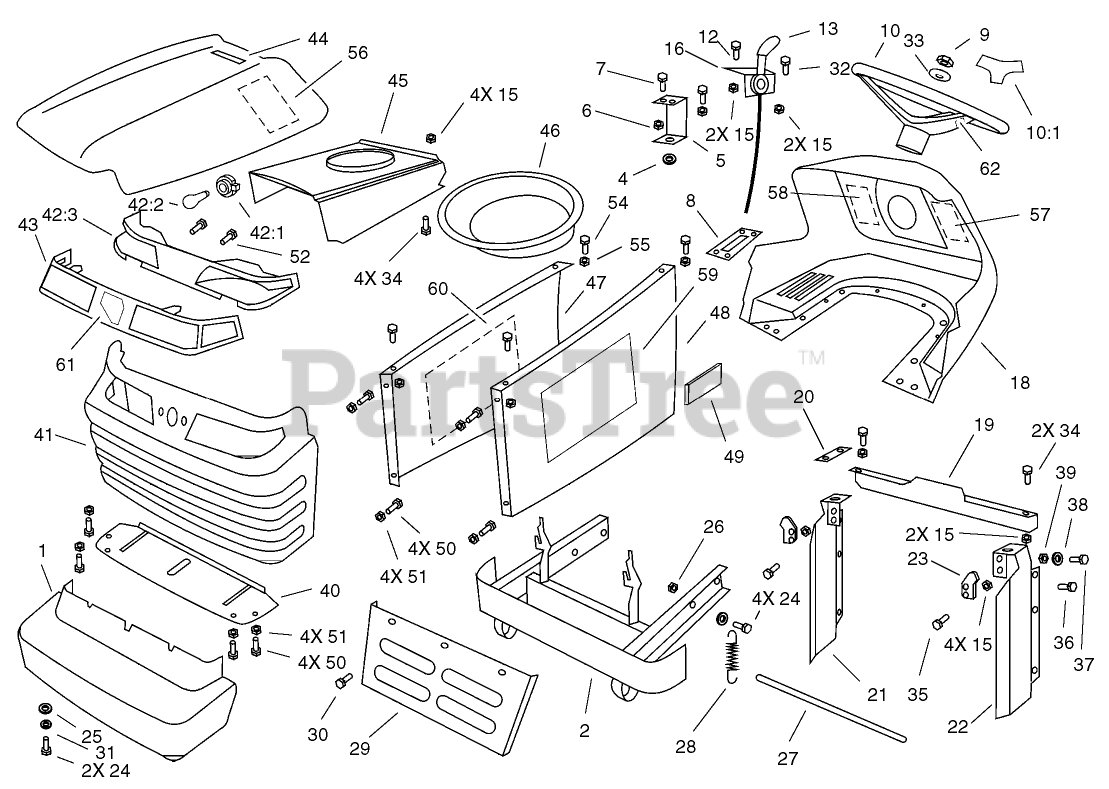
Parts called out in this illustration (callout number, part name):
5	HOLDER-TANK, FUEL
6	NUT-LOCK
9	NUT-HEX
10	WHEEL-STEERING
10:1	COVER-WHEEL, STEERING
12	SCREW-FLAT HEAD
15	NUT-LOCK
16	CABLE-THROTTLE AND CHOKE
18	PANEL-DASH
20	BRACKET
21	PANEL-RIGHT
22	PANEL-LEFT
23	LATCH-HOOD
24	SCREW-HH
25	WASHER-PLAIN
26	NUT-LOCK, NI
27	BAR-SAFETY
28	SPRING-HOOD
30	SCREW-TAP
31	WASHER-SPRING
33	Washer
38	WASHER
39	NUT-HEX
42:2	BULB
42:3	REFLECTOR-LIGHT
43	LENS - HEADLIGHT
49	FOAM-SIDEPANEL
51	NUT-HEX
52	SCREW-PLASTITE
54	SCREW-HWH
56	FOAM-HOOD
57	DECAL-PTO
58	DECAL-CHOKE/THROTTLE/KEY
62	DECAL
